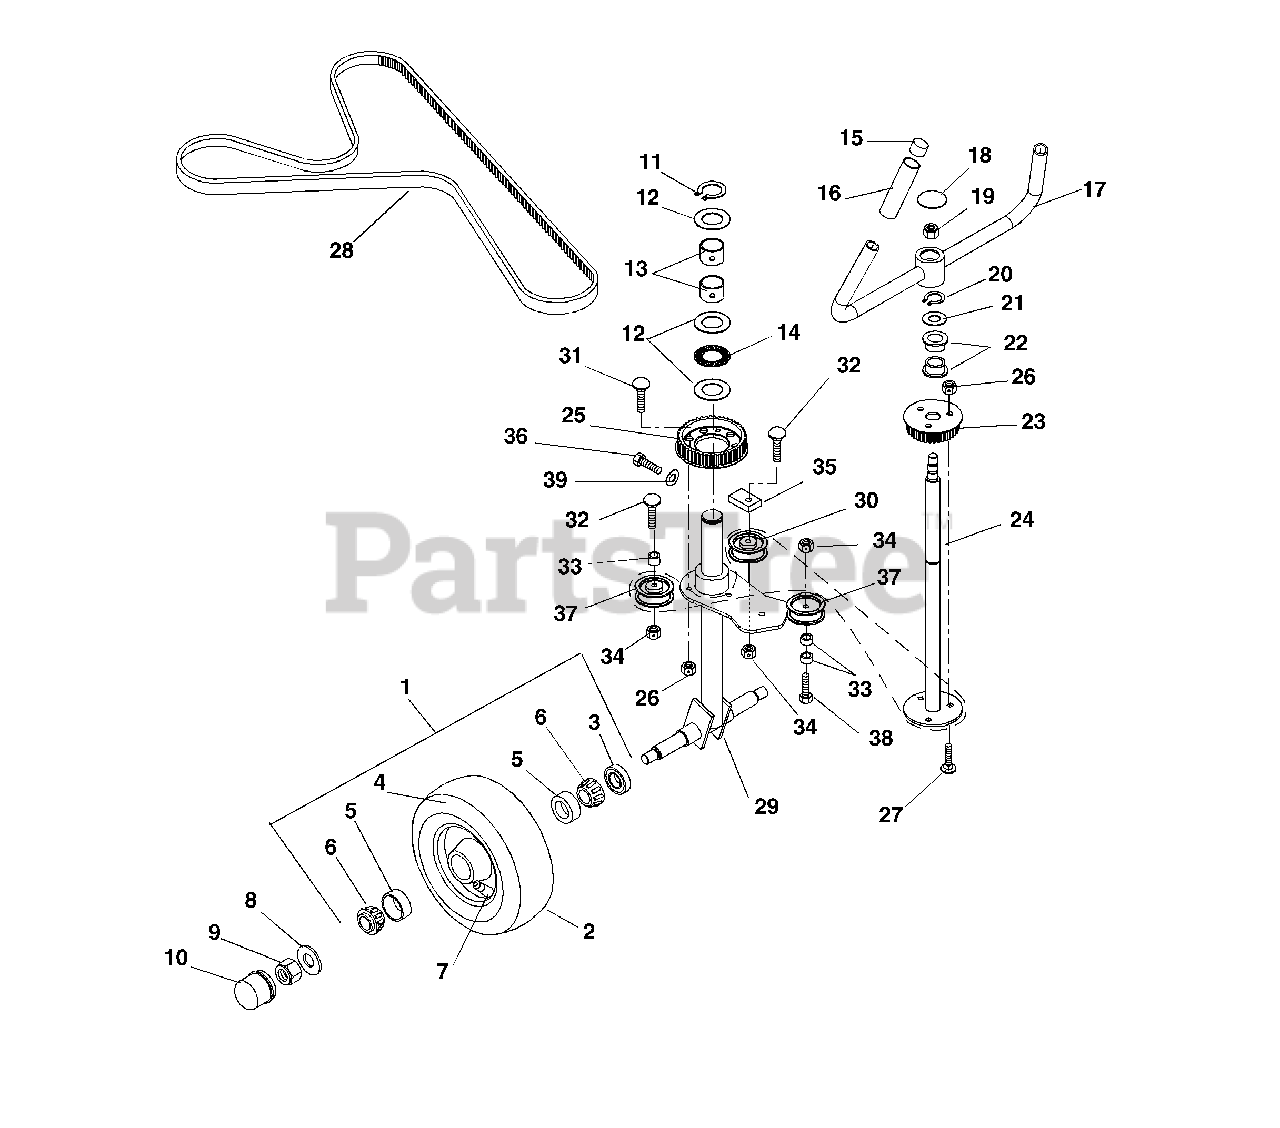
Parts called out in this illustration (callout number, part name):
1	Tire/Wheel Assembly 6.50-8
2	Tire, 16 x 6.5-8 4-Pulley Rib Tread
3	Seal
4	Wheel Assembly 3.75 x 8
5	Bearing-Cup 1.980 x 4.20
6	Bearing-Cone 1.0 x .58
7	Valve Stem Assembly
8	Washer, Flat-Steel .812 x 1.50 x .135
9	Nut, Locking-Center .75-10
10	Cap, Dust
11	Ring, Retaining-External 1.50 x 1.38
12	Washer-Thrust 1.502 x 2.18 x .063
13	Bearing-1.00 x 1.13 x 1.00
14	Bearing-Needle-Thrust 1.50 x 2.18 x .078
15	Caplug, Handlebar
17	Weldment, Handlebar
18	Hole Plug 1.38
19	Nut-Locking-Nylon .625-18
20	Ring-Retaining-External .906 x .078
21	Washer-Thrust 1.55 x 1.00 x .09
22	Bushing-Flange 1.02 x 1.38 x .75 x 1.75
23	Sprocket, Steering
24	Weldment, Steering Shaft
25	Sprocket, Drive
26	Nut-Locking-Center .31-18
27	Bolt-Round Head Square Neck .31-18 x 1.50 Grade 5
28	Belt, Double COG
29	Weldment, Caster Wheel
30	Idler- 2.25 x .87
31	Bolt-Round Head Square Neck .31-18 x 1.00 Grade 5
32	Bolt-Round Head Square Neck .38-16 x 2.00 Grade 2
33	Spacer .38 x .75 x .236
34	Nut-Locking-Nylon .38-16
35	Plate, Idler Adjustment
36	Bolt-Hex .31-24 x 1.50 Grade 5
37	Idler-Flat 2.75 x .38
38	Bolt-Hex .38-16 x 2.00 Grade 5
39	Washer-Flat-Steel .344 x .688 x .065
